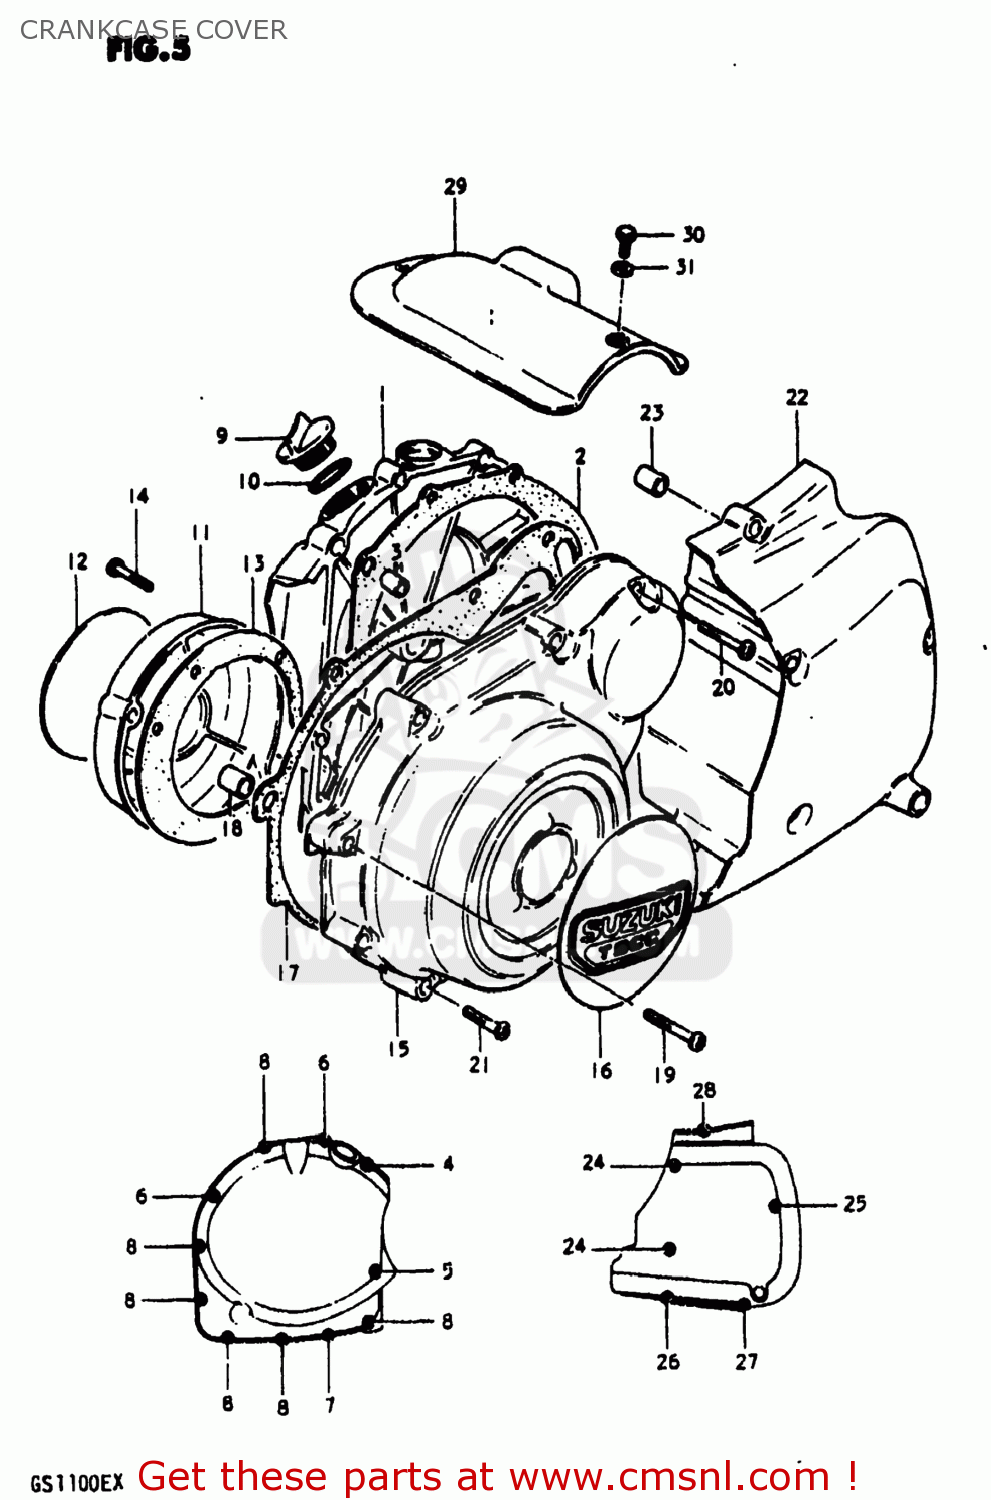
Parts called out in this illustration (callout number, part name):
1	COVER,CLUTCH
2	GASKET,CLUTCH COVER (MCA)
3	PIN
4	SCREW
5	SCREW (6X35)
6	SCREW 6X30
7	SCREW
8	SCREW
9	CAP
10	O RING(D:2.2,ID:32)
11	COVER,CONTACT BREAKER
12	EMBLEM
13	GASKET,CONTACT BREAKER COVER (NAS)
14	SCREW
15	COVER
16	EMBLEM,MAGNETO COVER
17	GASKET,MAGNETO COVER (MCA)
18	PIN
19	SCREW (6X45)
20	SCREW
21	SCREW 6X30
22	COVER,SPROCKET
23	PIN
24	SCREW (6*95)
25	SCREW 6X85
26	SCREW 6X70
27	SCREW
28	SCREW 6X30
29	COVER,STARTER MOTOR
30	BOLT
31	WASHER
